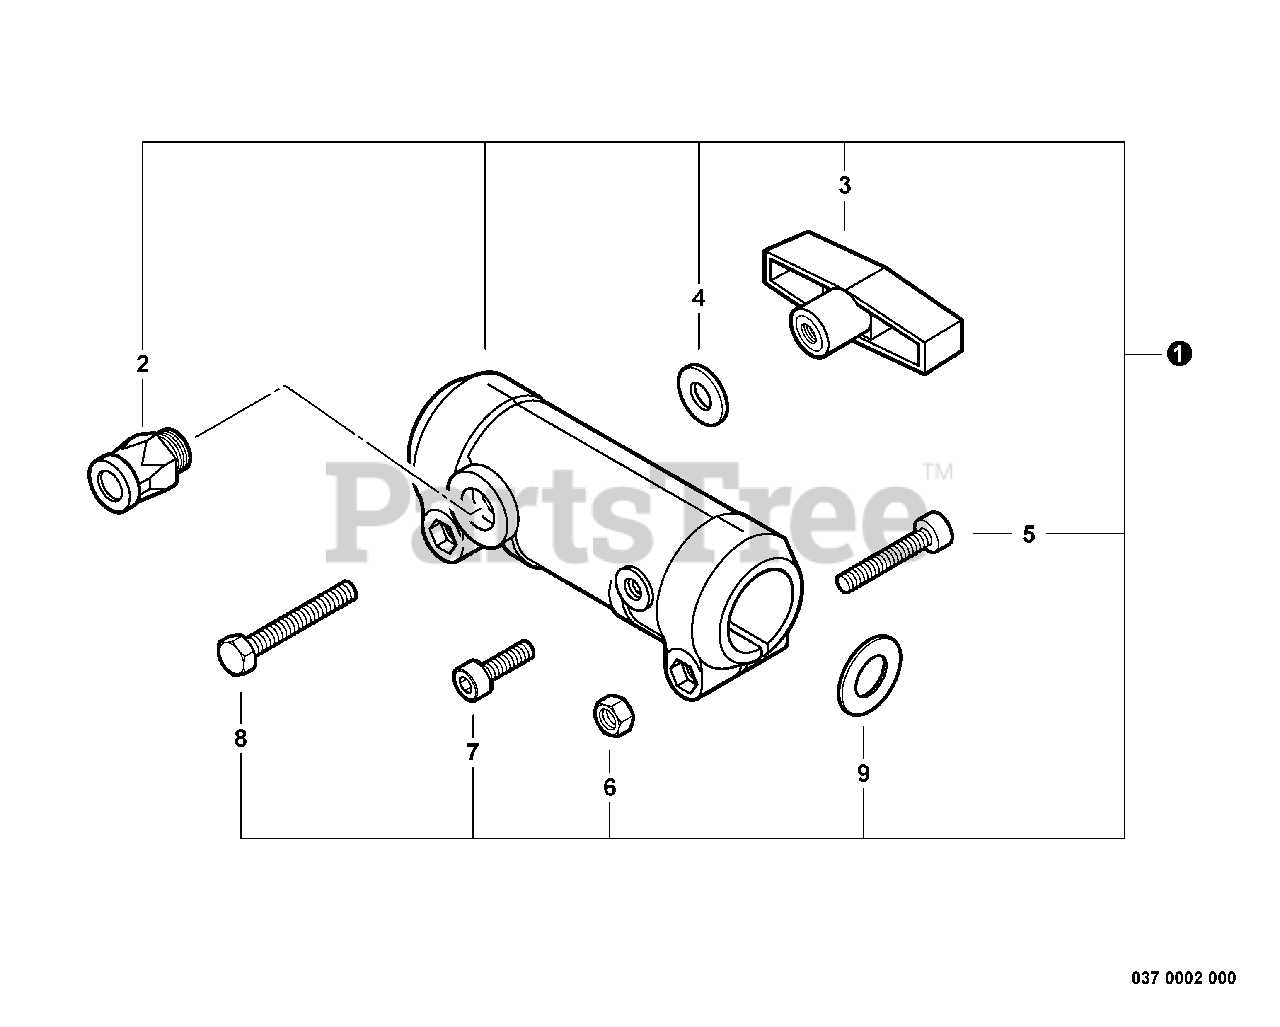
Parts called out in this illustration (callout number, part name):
1	COUPLER ASSY
2	LATCH ASSY
3	WINGNUT
4	WASHER - 6
5	SCREW - 6X25
7	SCREW - 5X10
8	BOLT - 6X40
9	WASHER - 18
